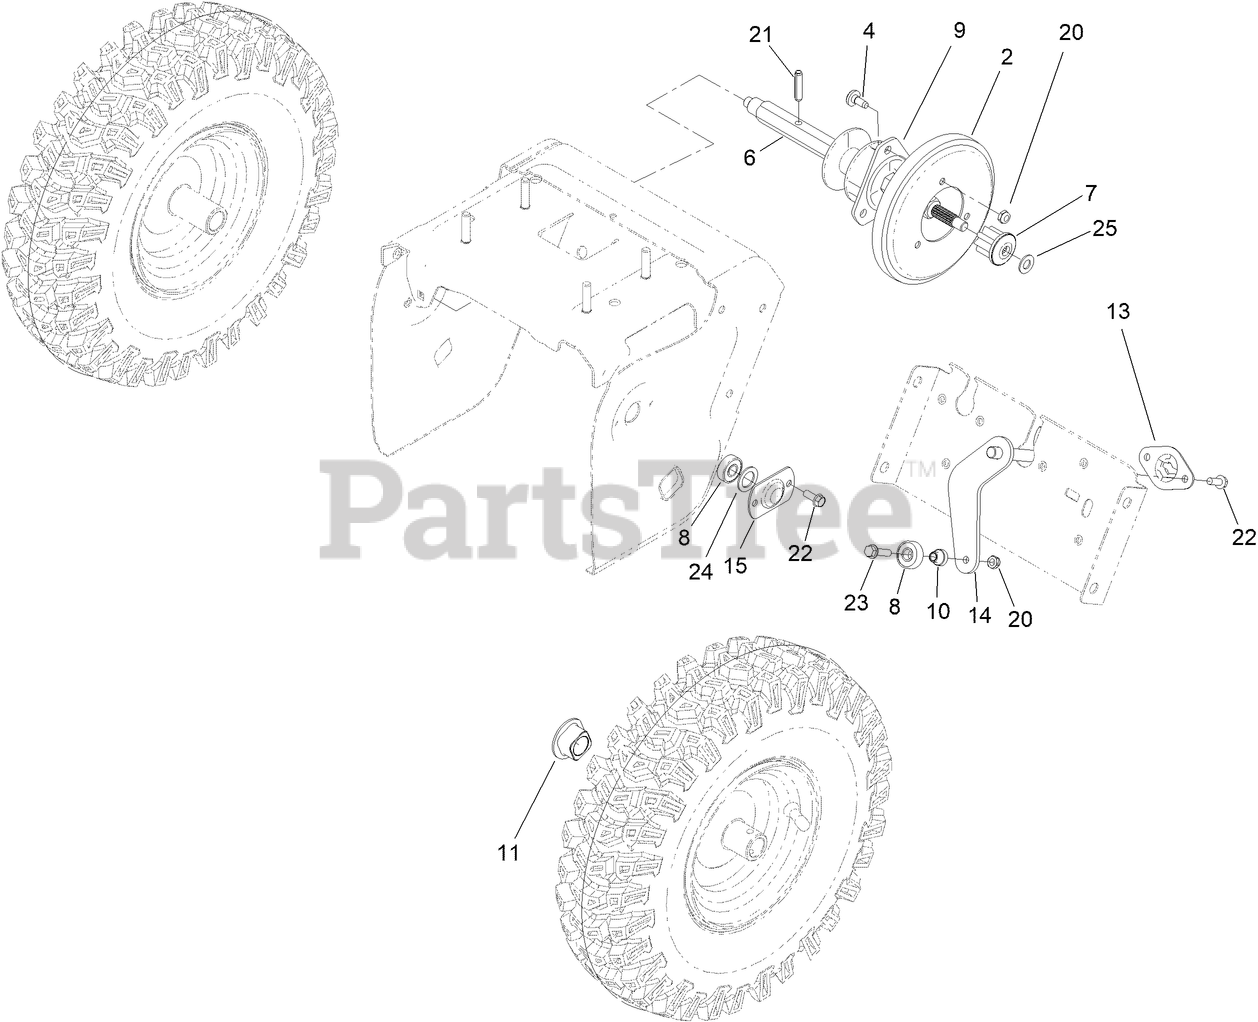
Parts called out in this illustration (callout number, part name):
2	WHEEL-FRICTION
4	SCREW-SHOULDER
6	SHAFT-HEX
7	GEAR-PINION, 8 TOOTH
8	BEARING-BALL
9	TRUNNION
10	SPACER-PLATE, SHIFT
11	BUSHING-AXLE
13	RETAINER-PLATE, SHIFT
14	SHIFT PLATE ASM
15	RETAINER-BEARING
20	NUT-LOCK, NI
21	PIN-ROLL, SLOTTED
22	SCREW-HWH
23	SCREW-HWHTF
24	WASHER-RUBBER
25	WASHER-FLAT
